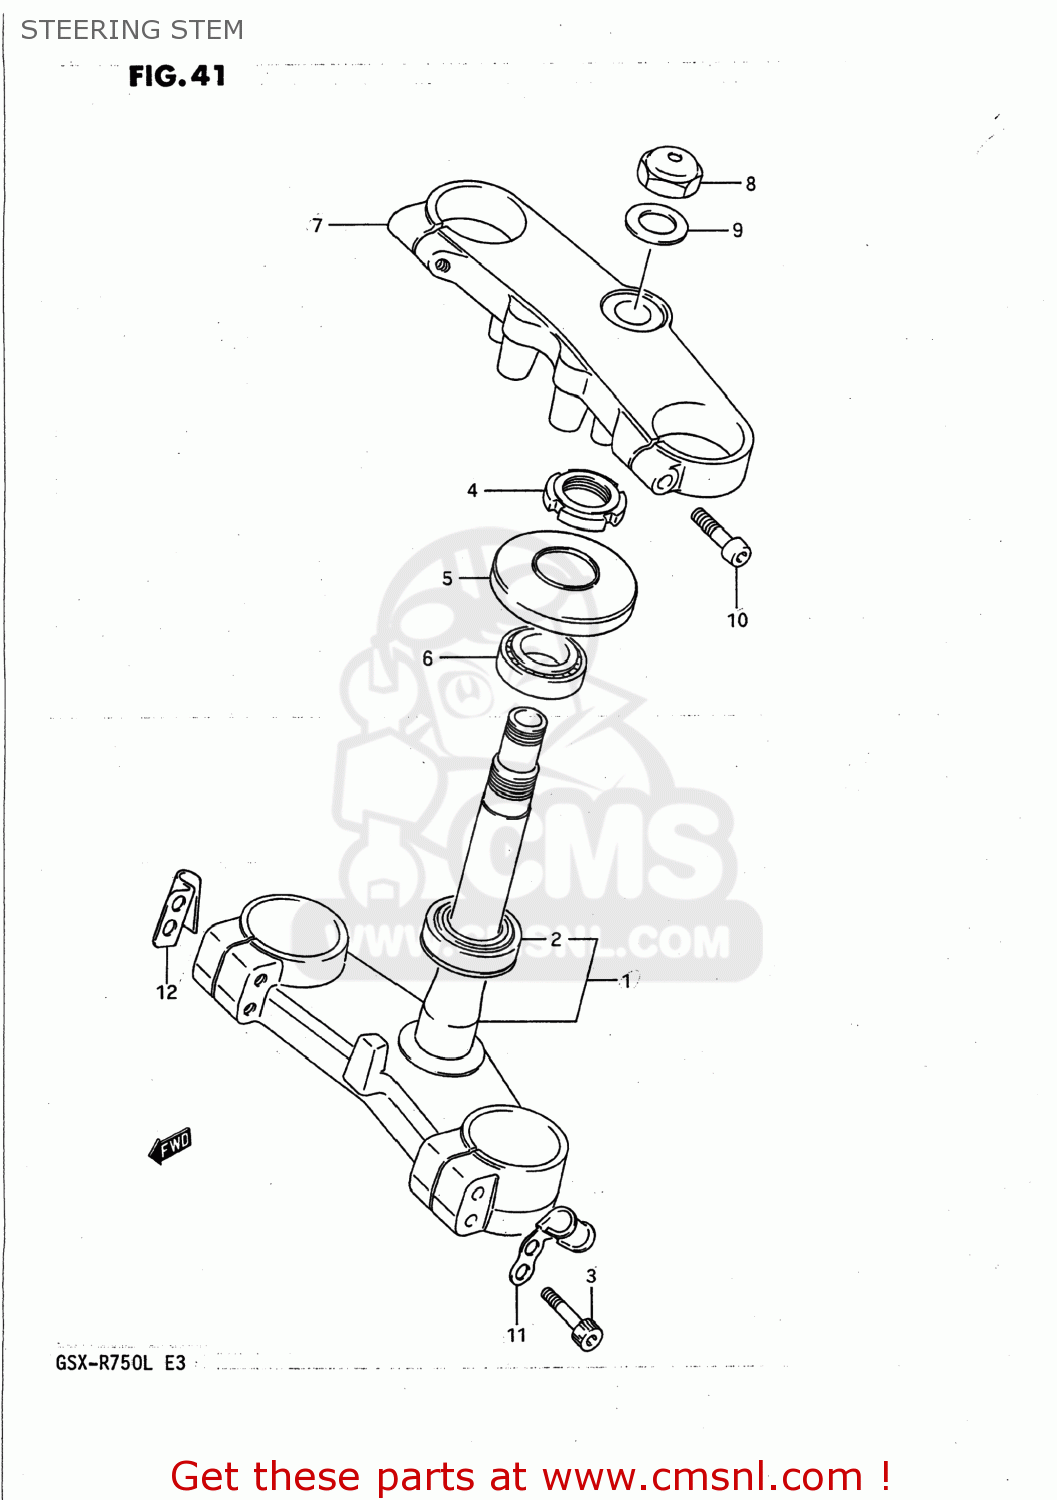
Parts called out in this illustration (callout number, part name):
1	STEM,STEERING
2	BEARING
3	BOLT
4	NUT,STEERING STEM(25X44X10)
5	SEAL OIL
6	TAPER,ROLLER BEARING
7	HEAD,STEERING STEM
8	NUT,STEM HEAD
9	WASHER
10	BOLT
11	CLAMP,SPEEDOMETER CABLE
12	CLAMP,CLUTCH CABLE
